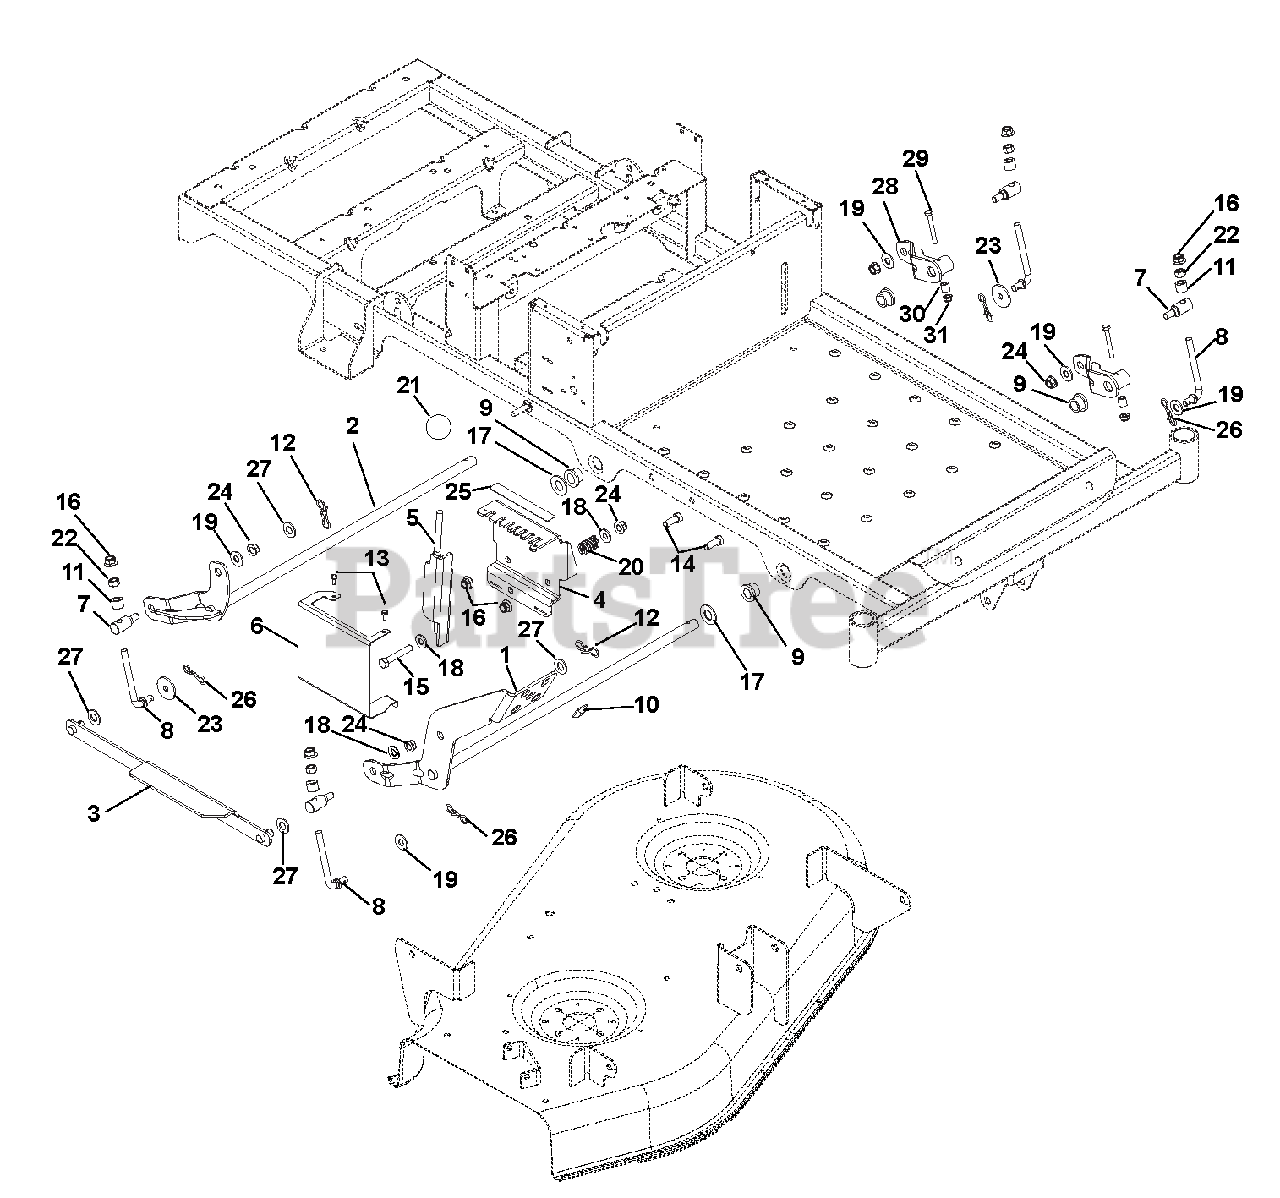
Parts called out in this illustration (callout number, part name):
1	WLDMT, FOOTPEDAL
2	WLDMT, REAR DECK LIFT
3	WMT, LIFT/HOC LINK
4	BRKT, HOC
5	WMT, HOC LEVER
6	GUARD, HOC
7	TRUNNION, DECK ADJUSTER
8	WIREFORM, DECK ADJUSTMENT
9	BSHG-FLG .629X.879X.469X1.250
11	BSHG-SLV .391X.688X.52 PM
12	PIN,BOW TIE LOCKING .091X1.875
13	@SCR-TAP 10-24X.50 HWH TR YWZC
14	@BLT-HEX .38-16X1.00 GR5 YWZC
15	@BLT-HEX .38-16X2.25 GR5 YWZC
16	@NUT-LK-NYL-FLG .38-16 YWZC
17	@WSHR-FL-STL.656X1.31X.095 YWZ
18	@WSHR-FL-STL.38X.875X.083 YWZC
19	@WSHR-FL-STL.406X.812X.065 YWZ
20	SG-COMP .125X.781X1.250
21	KNOB,BALL -BLACK 1.47" .375-16
22	@NUT-HEX .38-16 YWZC
23	WSHR-FL-STL .380X1.50X.125YWZC
24	@NUT-LK-TOP-FLG .38-16 YWZC
25	DECAL, HEIGHT OF CUT
26	PIN, BOW TIE LOCKING
27	WSHR-FL-NYL .518X1.000X.080
28	WLDMT, DECK LIFT ARM
29	@BLT-HEX .25-20X2.00 GR5 YWZC
30	BSHG-SLV .265X.500X.500
31	@NUT-LK-NYL-FLG .25-20 YWZC
